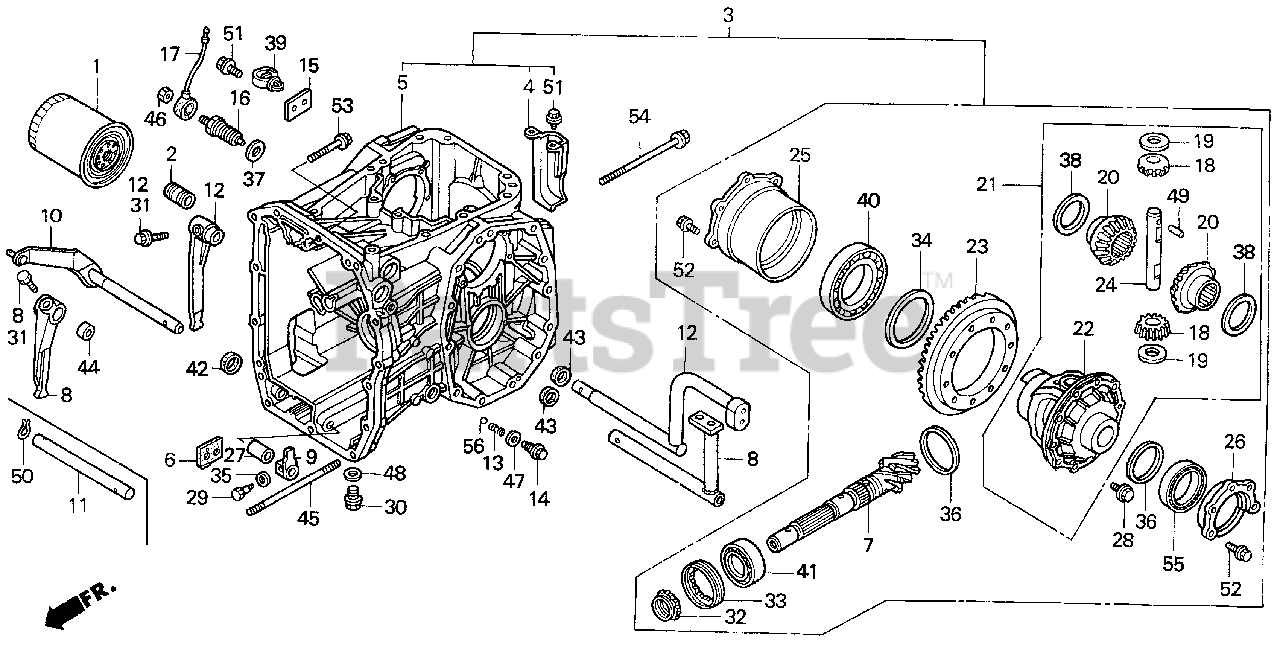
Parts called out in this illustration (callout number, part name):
1	FILTER, OIL
2	HOLDER, OIL FILTER
3	CASE ASSY., RR. TRANSMISSION
4	PLATE, OIL GUIDE
5	CASE, RR. TRANSMISSION
6	PLATE, SUCTION
7	SHAFT, FINAL
8	JOINT SET, AUXILIARY LEVER
9	ARM, SHIFT (2/4WD)
10	SHAFT, CHANGE (2/4WD)
12	JOINT SET, P.T.O. LEVER
13	SPRING, BALL SETTING
14	SCREW, BALL SPRING SETTING
15	BRACKET, WIRE HARNESS CLIP
16	SWITCH, REVERSE (TOYO)
17	WIRE, NEUTRAL SWITCH
18	GEAR, DIFFERENTIAL PINION
19	WASHER A, DIFFERENTIAL PINION (0.7MM)
19	WASHER B, DIFFERENTIAL PINION (0.8MM)
19	WASHER C, DIFFERENTIAL PINION (0.9MM)
19	WASHER D, DIFFERENTIAL PINION (1.0MM)
19	WASHER E, DIFFERENTIAL PINION (0.75MM)
19	WASHER F, DIFFERENTIAL PINION (0.85MM)
19	WASHER G, DIFFERENTIAL PINION (0.95MM)
20	PINION, RR. DRIVE
21	DIFFERENTIAL SUB-ASSY.
22	CASE, RR. DIFFERENTIAL
23	GEAR, RR. DIFFERENTIAL DRIVEN
24	SHAFT, PINION
25	HOLDER, R. DIFFERENTIAL BEARING
26	HOLDER, L. DIFFERENTIAL BEARING
27	COLLAR (17.3X28)
28	BOLT, HEX. (10MM)
29	BOLT, SPECIAL (8X22)
30	BOLT, PLUG (14MM)
31	BOLT, CHANGE ARM
32	NUT, LOCK (30MM)
33	NUT, LOCK (64MM)
34	SHIM A, R. RR. DIFFERENTIAL (1.00)
34	SHIM B, R. RR. DIFFERENTIAL (1.05)
34	SHIM C, R. RR. DIFFERENTIAL (1.10)
34	SHIM D, R. RR. DIFFERENTIAL (1.15)
34	SHIM E, R. RR. DIFFERENTIAL (1.20)
34	SHIM F, R. RR. DIFFERENTIAL (1.25)
34	SHIM G, R. RR. DIFFERENTIAL (1.30)
34	SHIM H, R. RR. DIFFERENTIAL (1.35)
34	SHIM I, R. RR. DIFFERENTIAL (1.40)
34	SHIM J, R. RR. DIFFERENTIAL (1.45)
34	SHIM K, R. RR. DIFFERENTIAL (1.50)
34	SHIM L, R. RR. DIFFERENTIAL (1.55)
34	SHIM M, R. RR. DIFFERENTIAL (1.60)
34	SHIM N, R. RR. DIFFERENTIAL (1.65)
34	SHIM O, R. RR. DIFFERENTIAL (1.70)
34	SHIM P, R. RR. DIFFERENTIAL (1.75)
34	SHIM Q, R. RR. DIFFERENTIAL (1.80)
34	SHIM R, R. RR. DIFFERENTIAL (1.85)
34	SHIM S, R. RR. DIFFERENTIAL (1.90)
34	SHIM T, R. RR. DIFFERENTIAL (1.95)
34	SHIM U, R. RR. DIFFERENTIAL (2.00)
35	WASHER, CONICAL SPRING (8MM)
36	SHIM A, L. RR. DIFFERENTIAL (1.00)
36	SHIM B, L. RR. DIFFERENTIAL (1.05)
36	SHIM C, L. RR. DIFFERENTIAL (1.10)
36	SHIM D, L. RR. DIFFERENTIAL (1.15)
36	SHIM E, L. RR. DIFFERENTIAL (1.20)
36	SHIM F, L. RR. DIFFERENTIAL (1.25)
36	SHIM G, L. RR. DIFFERENTIAL (1.30)
36	SHIM H, L. RR. DIFFERENTIAL (1.35)
36	SHIM I, L. RR. DIFFERENTIAL (1.40)
36	SHIM J, L. RR. DIFFERENTIAL (1.45)
36	SHIM K, L. RR. DIFFERENTIAL (1.50)
36	SHIM L, L. RR. DIFFERENTIAL (1.55)
36	SHIM M, L. RR. DIFFERENTIAL (1.60)
36	SHIM N, L. RR. DIFFERENTIAL (1.65)
36	SHIM O, L. RR. DIFFERENTIAL (1.70)
36	SHIM P, L. RR. DIFFERENTIAL (1.75)
36	SHIM Q, L. RR. DIFFERENTIAL (1.80)
36	SHIM R, L. RR. DIFFERENTIAL (1.85)
36	SHIM S, L. RR. DIFFERENTIAL (1.90)
36	SHIM T, L. RR. DIFFERENTIAL (1.95)
36	SHIM U, L. RR. DIFFERENTIAL (2.00)
37	WASHER, NEUTRAL SWITCH
38	WASHER, THRUST (30.3X50X1.5)
39	CLIP, WIRE HARNESS (25MM)
40	BEARING, RADIAL BALL (6012)
41	BEARING, RADIAL BALL (5206V12)
42	OIL SEAL (14X24X6) (ARAI)
43	OIL SEAL (22X31X5) (ARAI)
44	COLLAR (22.2X28X11)
45	BOLT, STUD (10X90)
46	NUT, HEX. (4MM)
47	WASHER, DRAIN PLUG (12MM)
48	WASHER, DRAIN PLUG (14MM)
49	PIN, SPRING (4X28)
51	BOLT, FLANGE (6X12)
52	BOLT, FLANGE (8X25)
53	BOLT, FLANGE (10X35)
54	BOLT, FLANGE (10X90)
55	BEARING, RADIAL BALL (6010)
56	BALL, STEEL (#10) (5/16)
